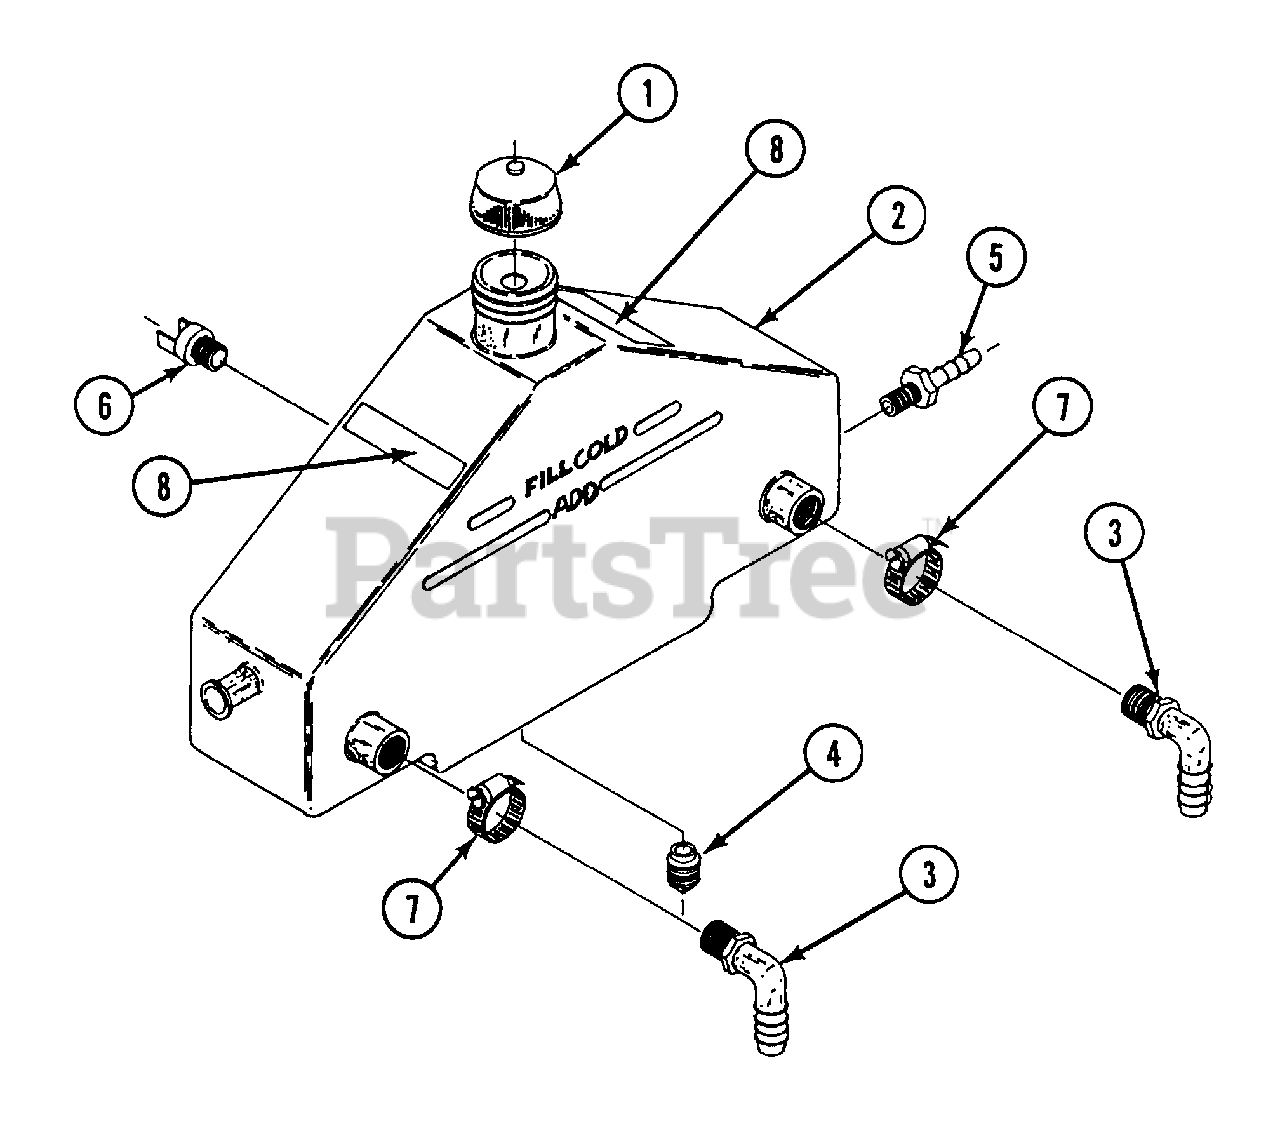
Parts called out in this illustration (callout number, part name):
1	OIL CAP
2	OIL TANK, NYLON
3	ELBOW, 3/4 HOSE X 1/2 NPTM
4	MAGNETIC PLUG, 1/2 NPTM NYLON
5	HOSE BARB, 1/4 HOSE X 1/8 NPTM
6	TEMPERATURE SWITCH ASSEMBLY
7	HOSE CLAMP, 1/2 - 1-1/4 HOSE
8	DECAL, "TRANSMISSION FLUID"
